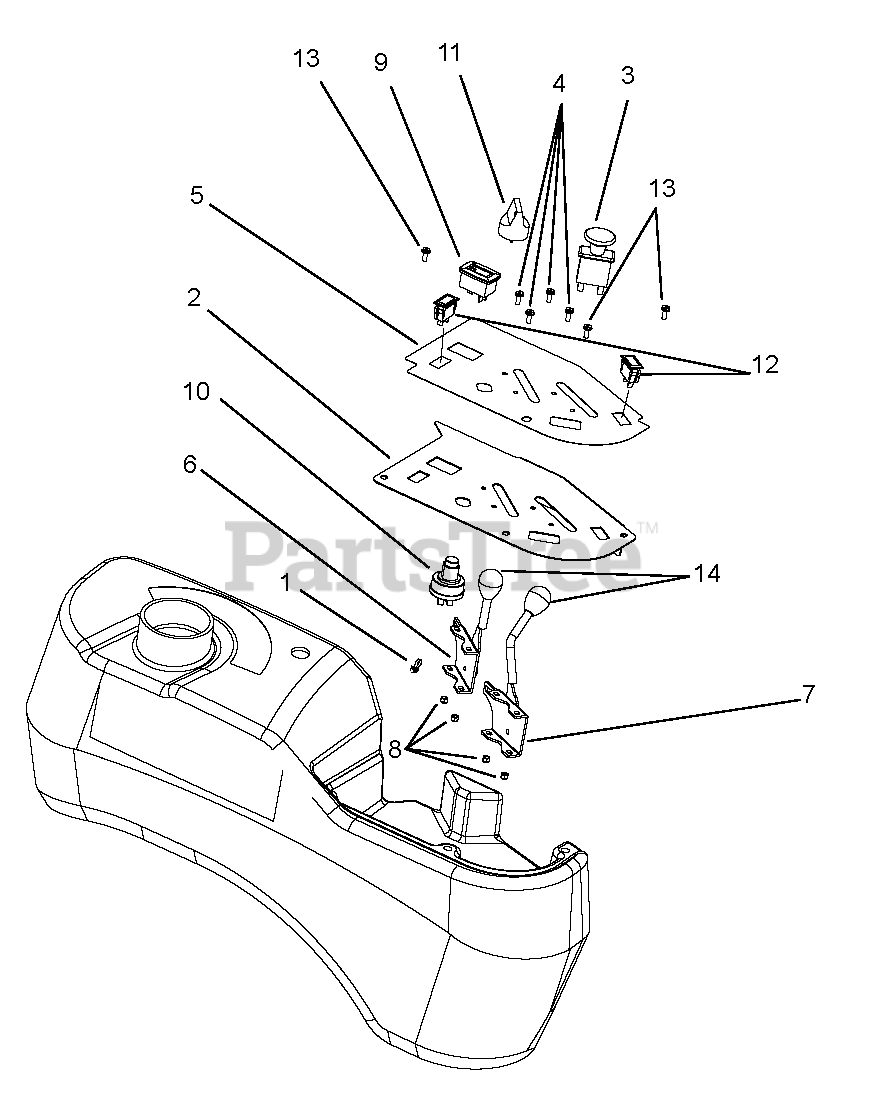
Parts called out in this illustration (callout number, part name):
1	Cable Tie w/ Tree (.25 HOLE)
2	Panel, Control
3	Switch, Clutch
4	Screw, Machine 10-24X.50 Hex Washer Head
5	Decal, Control Panel
6	Cable, Pro-Control Choke
7	Cable, Pro-Control Throttle
8	Nut, Locking Nylon 10-24 W/INSRT YWZC
9	Meter, Hour with Maintenance
10	Switch, Ignition
11	Key, wtih Shield
12	Light, Indicator
13	Screw, Machine 10-24 x .50 Hex Washer Head Stainless
14	Knob, Control, Black .38-16 x .50
